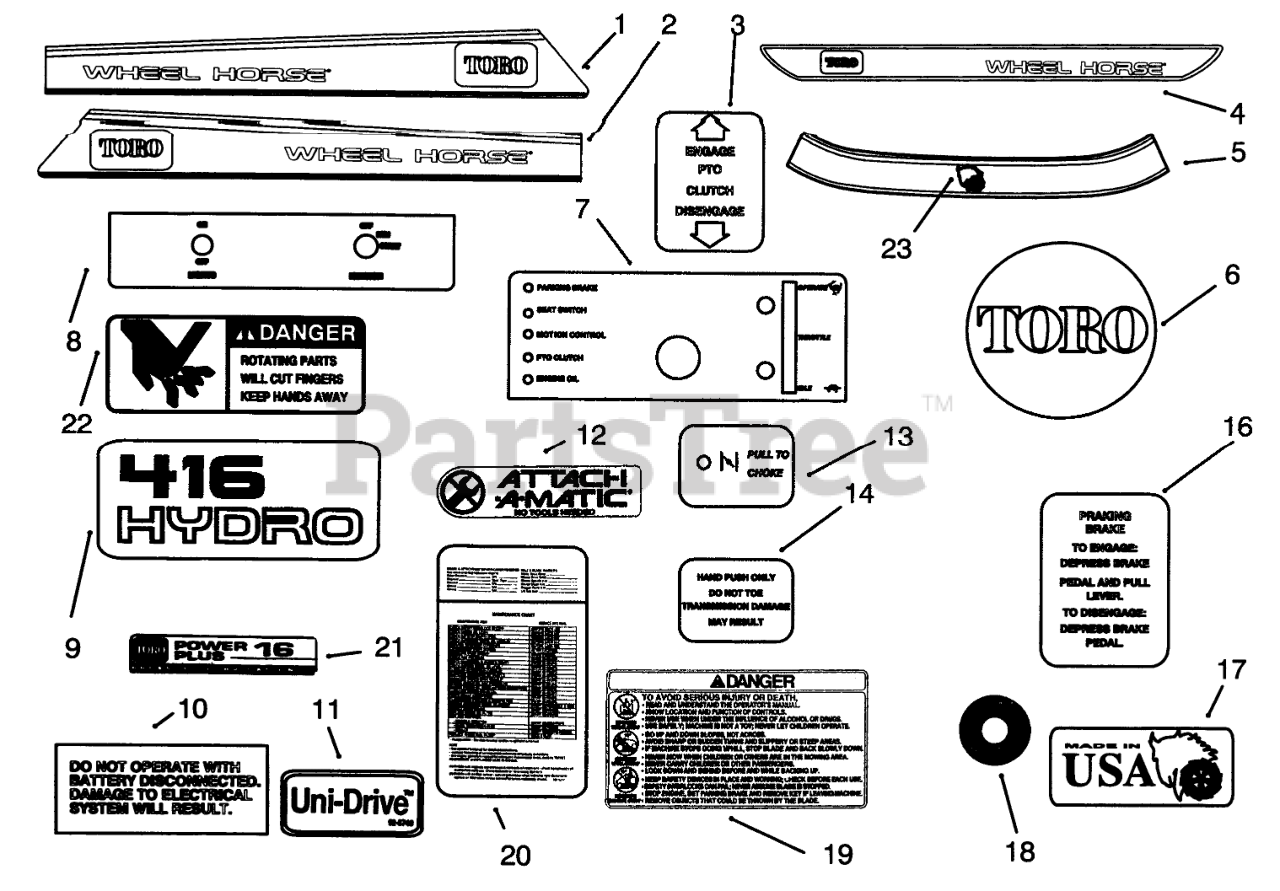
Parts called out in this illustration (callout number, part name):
1	DECAL - RH HOOD TOP
2	DECAL - LH HOOD TOP
3	DECAL PTO CLUTCH
4	DECAL - REAR FENDER
5	DECAL-FRONT HOOD, TOP
6	NAME-PLATE TORO LOGO
7	DECAL-DASH
8	DECAL-BACK PLATE
9	DECAL - MODEL 416-H
10	DECAL ELECT SYSTEM
11	Decal-Unidrive
12	DECAL-ATTACH A-MATIC
13	DECAL-CHOKE
14	DECAL-DO NOT TOW
16	DECAL-PARKING BRAKE
17	DECAL - USA
18	Decal-Air Cleaner
19	DECAL - DANGER
20	Decal-Maintenance
21	DECAL-PWR PLUS 16 PL
22	DECAL - DANGER
23	PLATE - LOGO WHL HORSE
